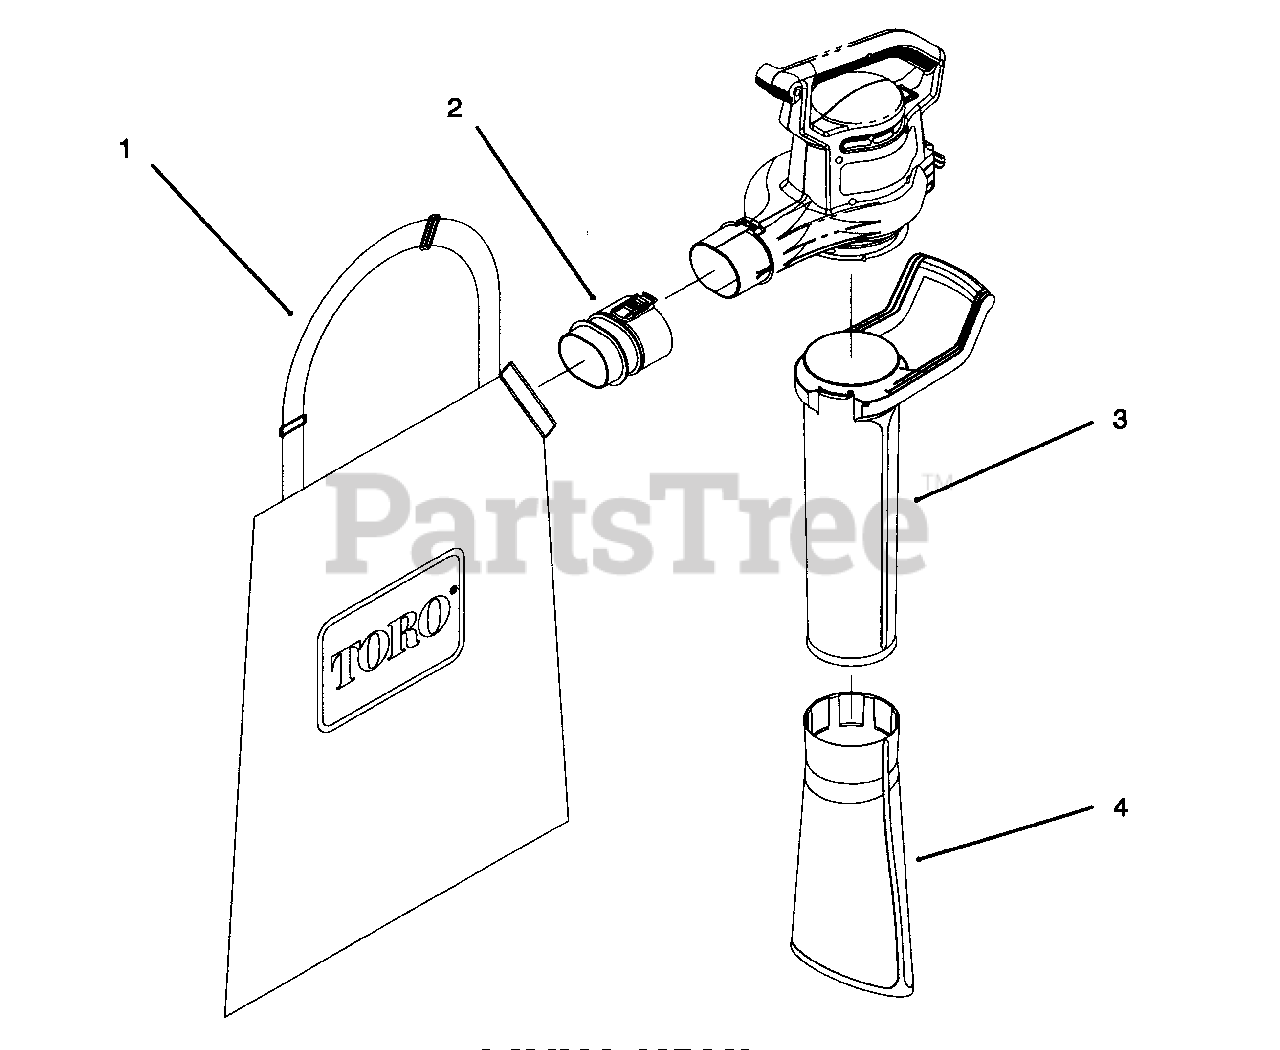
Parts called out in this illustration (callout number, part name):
1	Bag
2	Tube-Bag Inlet
3	Tube-Vac Upper
4	Tube-Vac Lower
